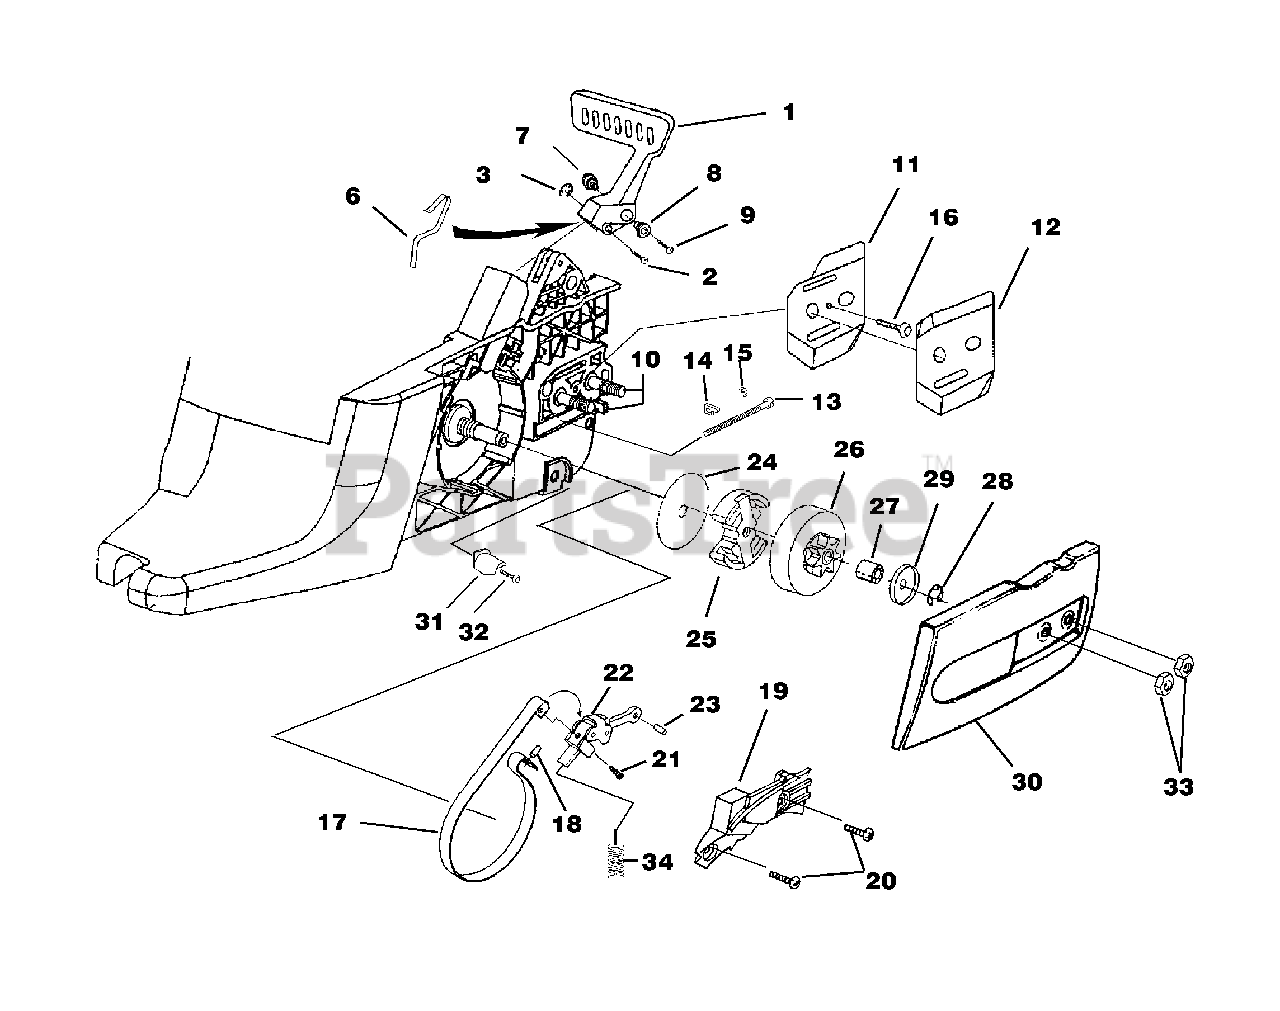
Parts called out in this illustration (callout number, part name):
1	Hand Guard Kit
2	Hand Guard Actuating Pin
3	Retaining Ring
6	Spring, Handguard
7	Pivot, L.H.
8	Pivot, R.H.
9	Screw, Hex Socket Hd. (8-32 x 5/8")
10	Guide Bar Bolt
11	Plate, Guide Bar
12	Plate, Guide Bar
13	Screw, Guide Bar Adjusting
14	Pin, Guide Bar Adjusting
15	Ring, Retaining
16	Screw, Thread Form (6-19 x 1/2")
17	Chain Brake Kit
18	Pin, Roll
19	Cover, Chain Brake
20	Screw, Pan Hd. (6-19 x 1/2")
21	Screw, Pan Hd. (8-16 x .320)
22	Chain Brake Link
23	Pin, Roll
24	Thrust Washer
25	Clutch & Hardware
26	Sprocket, Drum (3/8 Pitch)
27	Bearing, Needle
28	Ring, Retaining
29	Washer, Cupped
30	Drive Case Cover
31	Stop, Chain
32	Screw, Thread Form (10-14 x 3/4")
33	Nut, Hex
34	Spring, Compression
